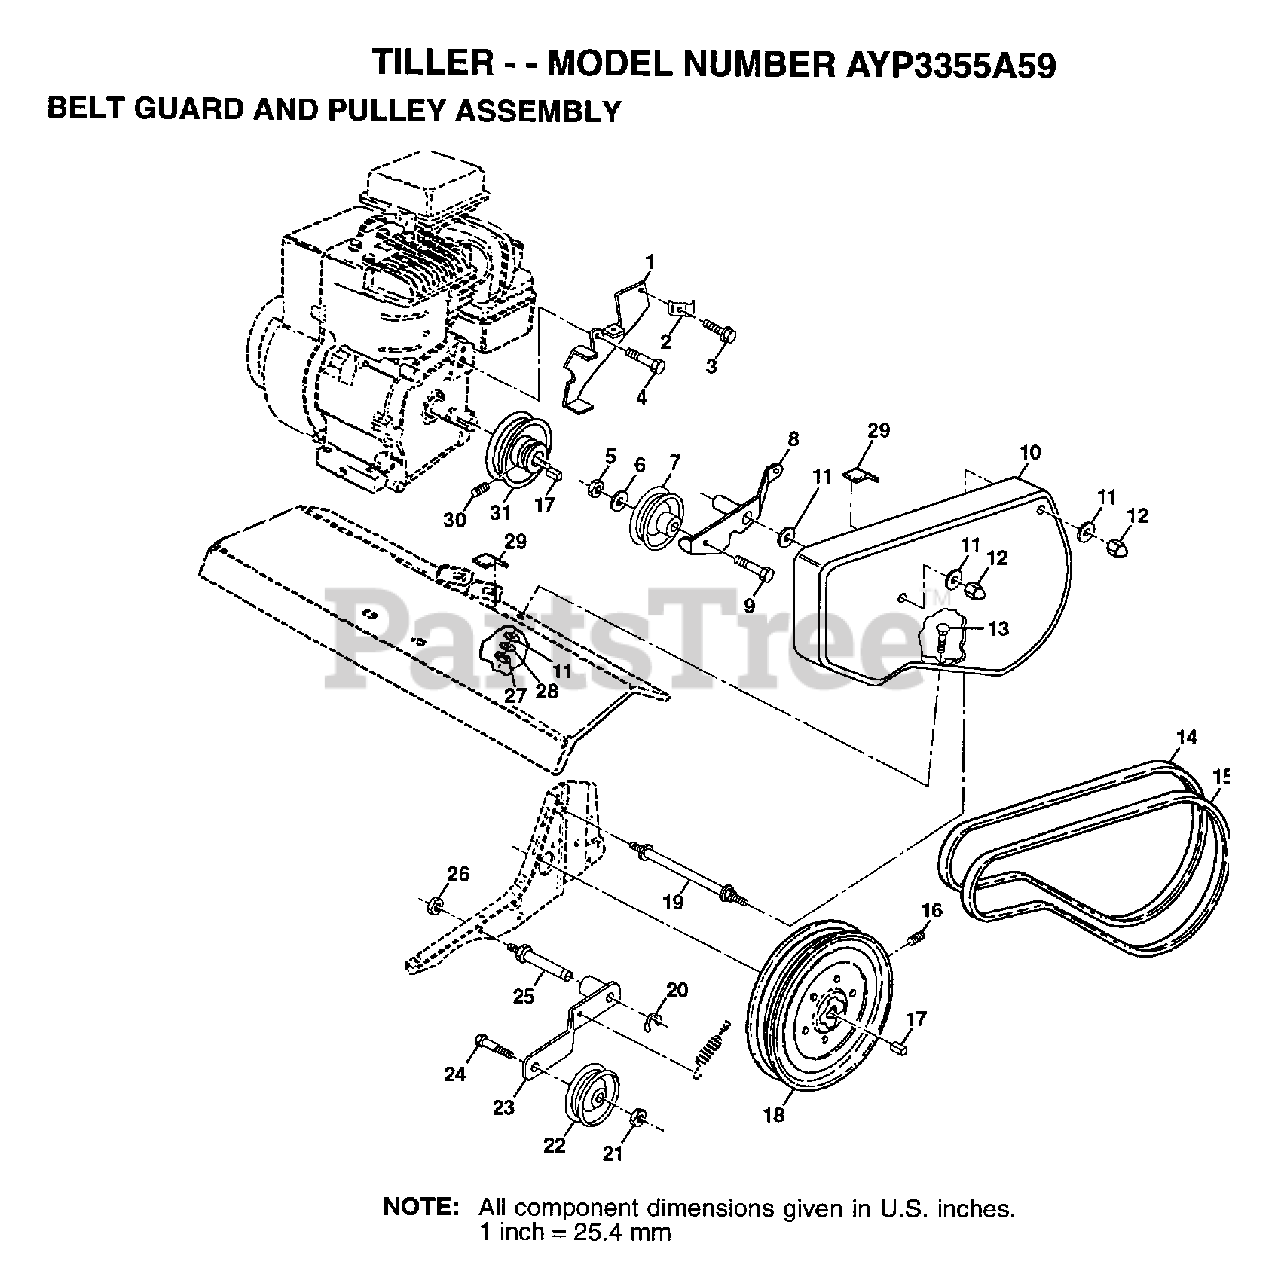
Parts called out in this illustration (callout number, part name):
2	CONDIUT CLIP T
5	NUT.HEX.3/8-16UNC
6	WASHER
7	PULLEY W/SPACER
8	ARM.ASM.REV.IDLER
10	GUARD.BELT.SILKSC
11	WASHER
12	NUT-CAP TI
13	BOLT T
14	BELT-V
16	SET SCREW
17	KEY T
19	BOLT TI
20	KLIP RING TI
21	NUT
23	IDLER ARM TI
25	SHAFT IDLER TI
26	JAM NUT TI
28	LOCKWASHER
29	PAD IDLER TI
30	SET SCREW
31	ENGINE PULLEY TI
